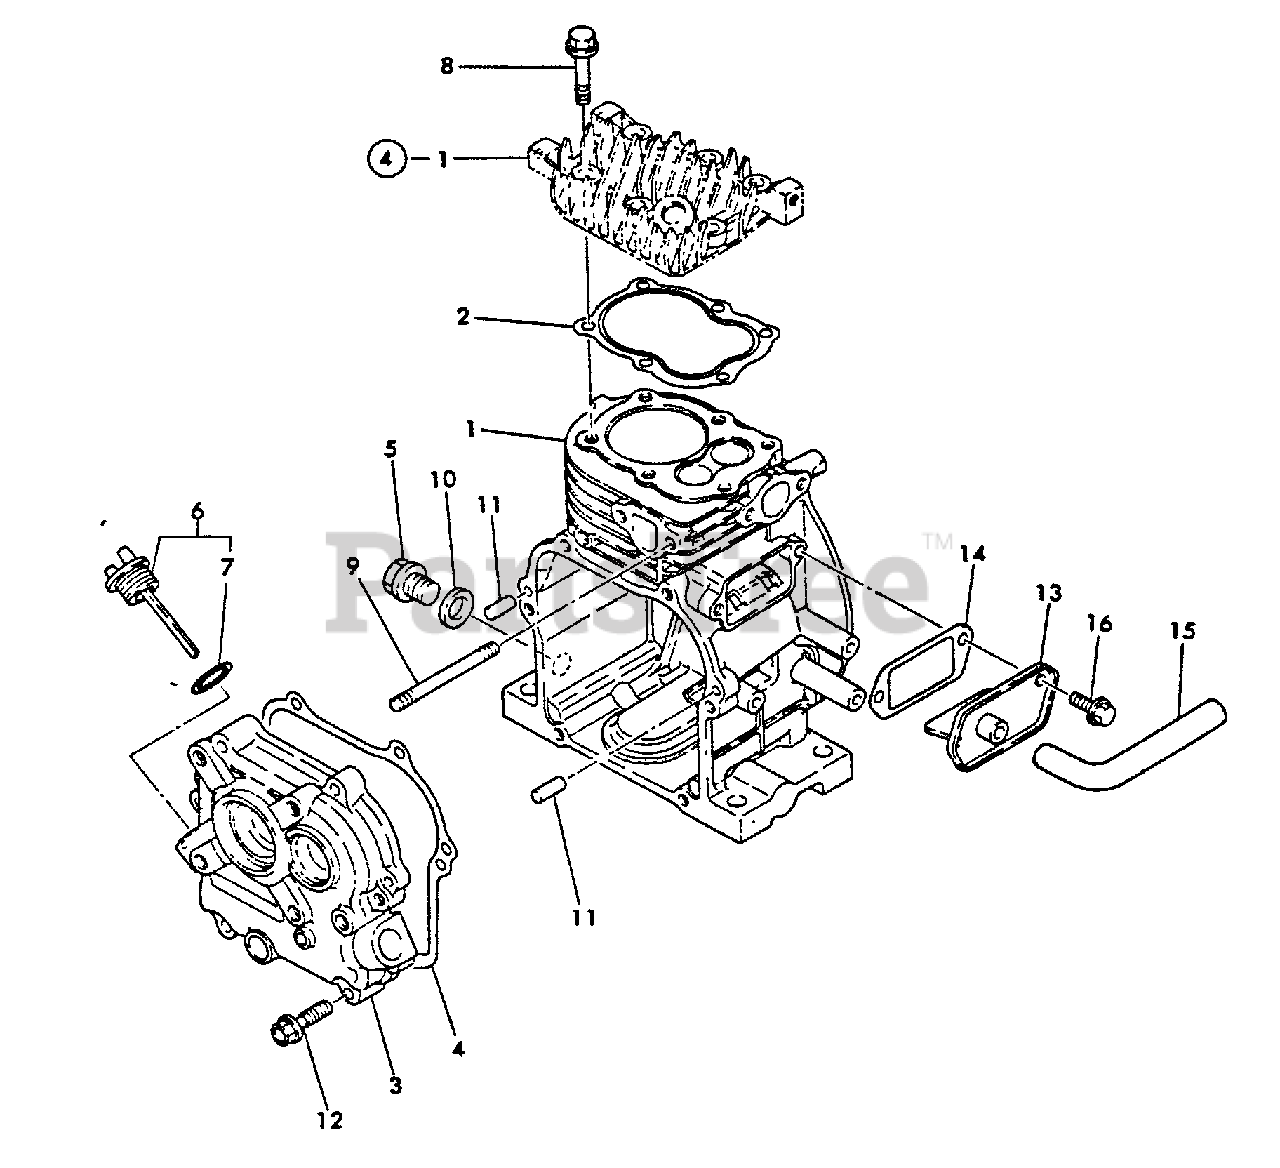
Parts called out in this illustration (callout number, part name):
1	CYLINDER ASSY
2	GASKET, CYLINDER
3	COVER, CRANKCASE
4	GASKET, CRANKCASE
5	PLUG, DRAIN
6	CAP ASSY
7	O-RING - 18
8	BOLT - 6X35
9	BOLT - 6X70
10	GASKET
11	PIN - 6X16
12	BOLT - 6X25
13	VENT, FUEL TANK
14	GASKET, BREATHER
15	PIPE - BREATHER
16	BOLT - 6X8 -- PLATED
